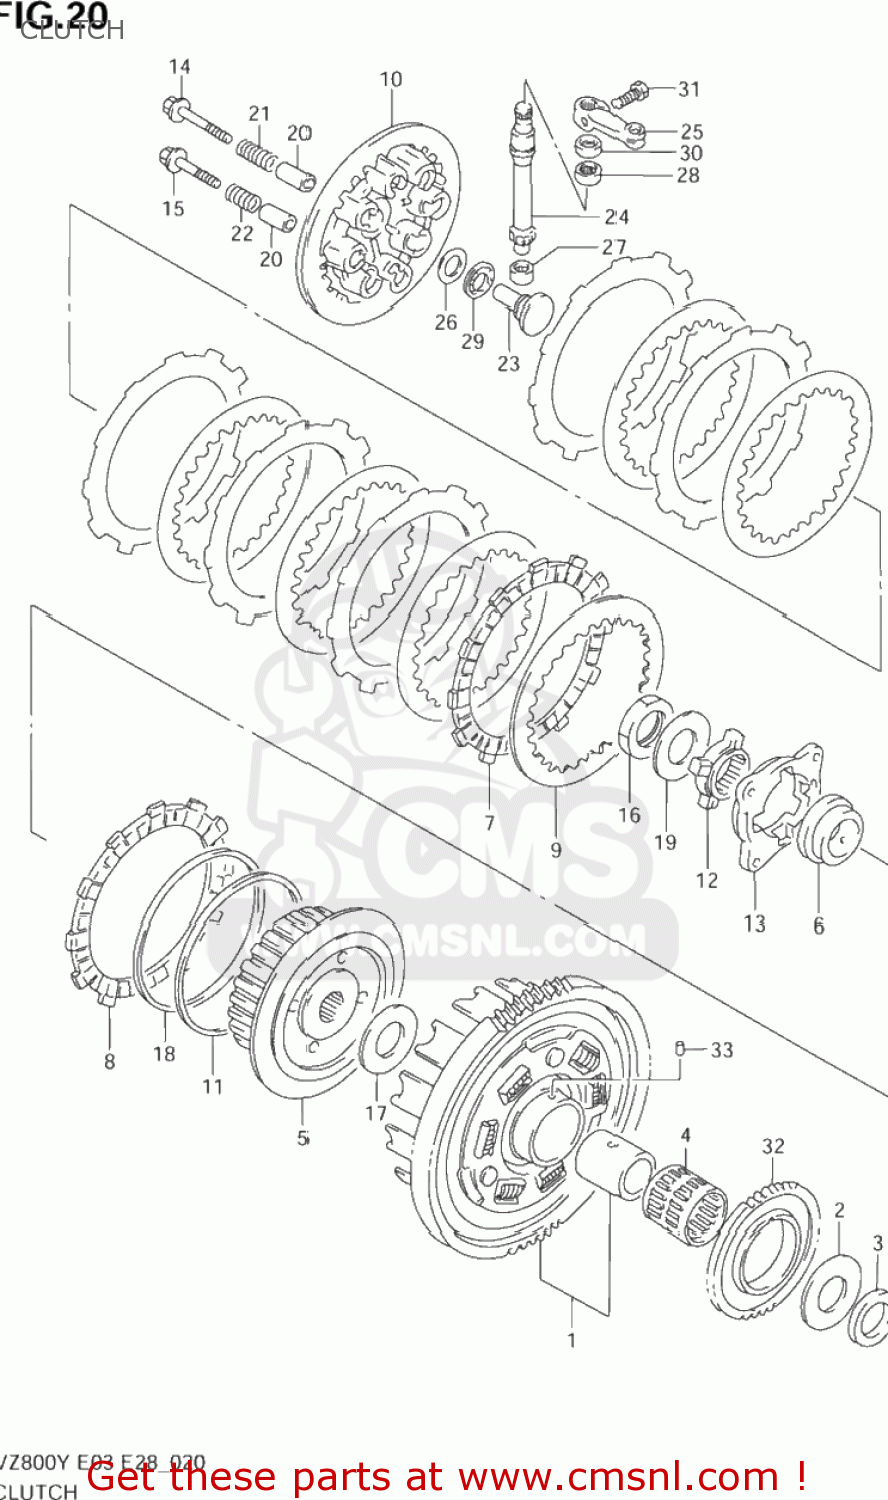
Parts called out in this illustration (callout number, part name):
1	GEAR ASSY,PRI DRIVEN
2	WASHER(25X54X2.5)
3	SPACER(25X38X6.5)
4	BEARING(35X40X35.8)
5	HUB,CLUTCH SLEEVE
6	SPACER,CLUTCH SLEEVE HUB
7	PLATE,CLUTCH DRIVE (NAS)
8	PLATE,CLUTCH DRIVE(T:3.5) (NAS)
9	PLATE,CLUTCH DRIVEN(T:1.6) (NAS)
10	DISC,CLUTCH PRESSURE
11	SEAT,WAVE WASHER(T:1.4)
12	CAM,CLUTCH NO.1
13	CAM,CLUTCH NO.2
14	BOLT(6X40)
15	BOLT(6X32.5)
16	NUT
17	WASHER(25X60X2.5)
18	WASHER
19	WASHER
20	SPACER(6.5X9X24.1)
21	SPRING
22	SPRING
23	RACK,CLUTCH RELEASE
24	PINION,CLUTCH RELEASE
25	ARM,CLUTCH RELEASE
26	WASHER(15.5X28X1)
27	BEARING(9X13X10)
28	BEARING(12X16X10)
29	BEARING(15X28X2)
30	SEAL,OIL(10X17X5)
31	BOLT
32	GEAR,OIL PUMP DRIVE(NT:47)
33	PIN(6X6)
